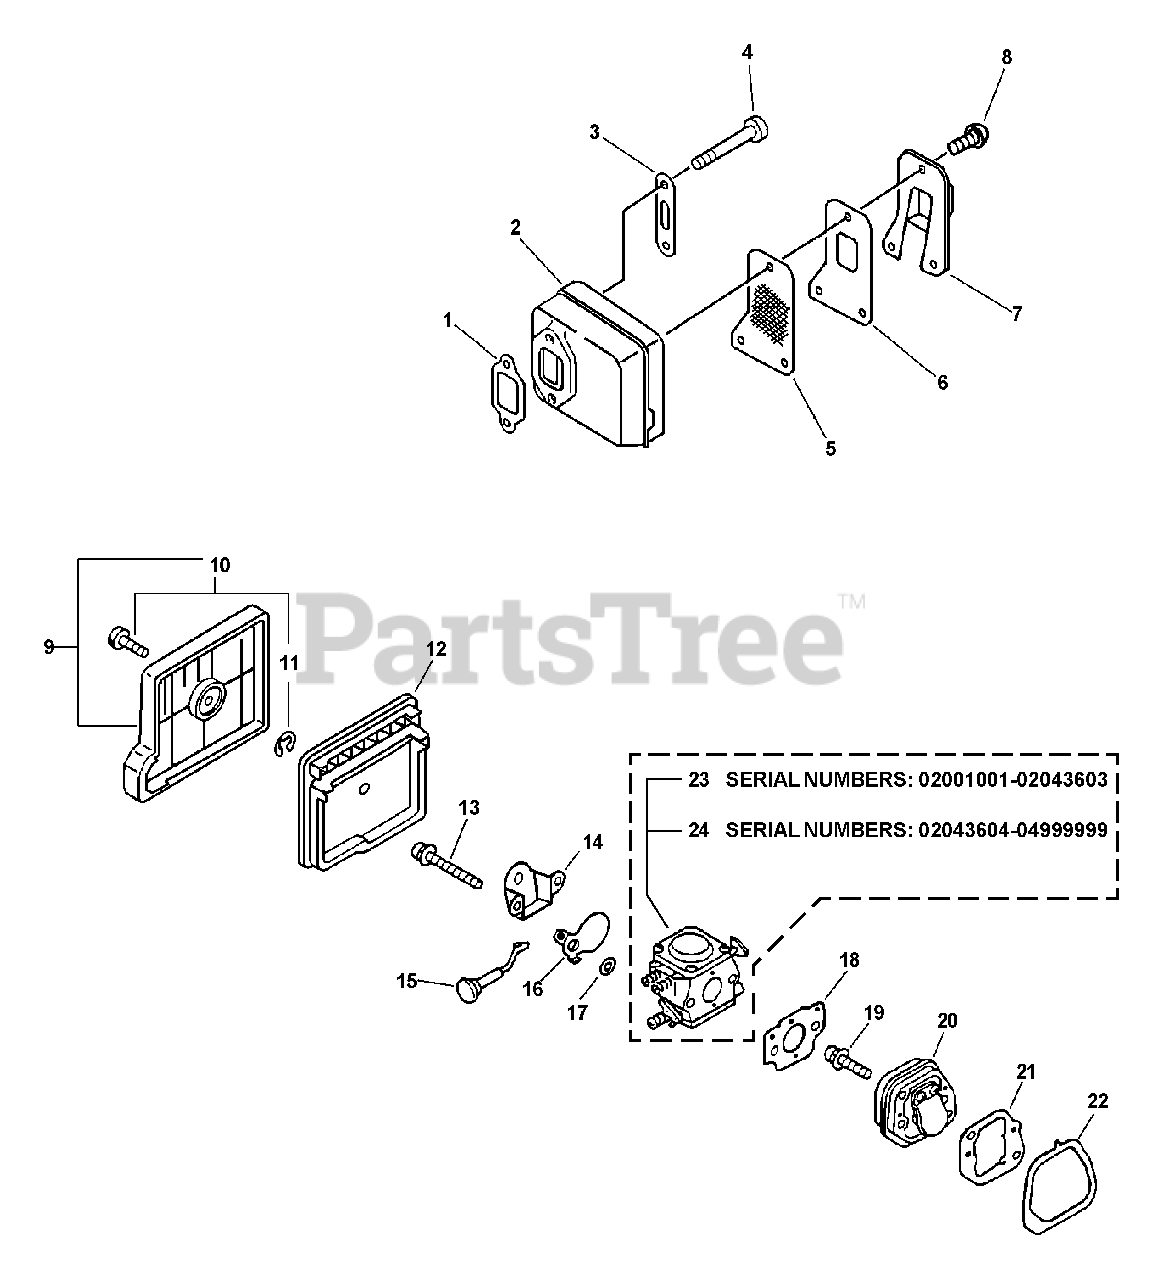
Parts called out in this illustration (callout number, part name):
1	GASKET, EXHAUST
2	MUFFLER
4	SCREW - 5X45
5	SCREEN, SPARK ARRESTOR
6	GASKET, EXHAUST
7	GUIDE, EXHAUST
8	SCREW - 4X12
9	AIR FILTER COVER ASSY
10	THUMBSCREW
11	RING, RETAINING - 4
12	FILTER, AIR
13	SCREW - 5X45
14	PLATE, PREVENT
15	ROD, CHOKE
16	SHUTTER, CHOKE
17	WASHER
18	GASKET, INTAKE
19	SCREW - 5X18
20	INSULATOR KIT
21	GASKET, INTAKE
22	SEAL
23	CARBURETOR WT-589
24	CARBURETOR WT-589
